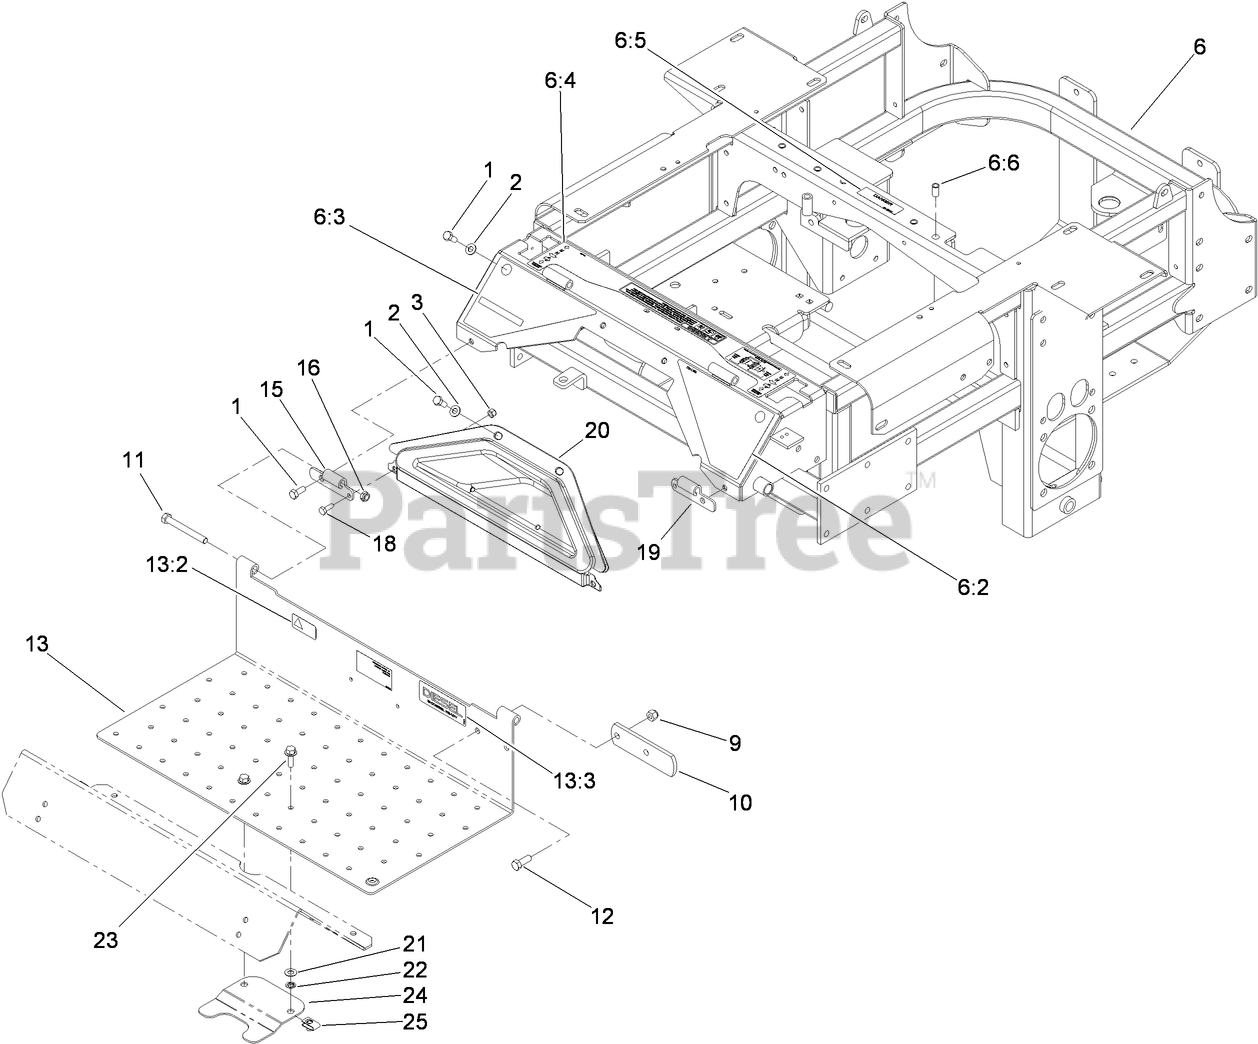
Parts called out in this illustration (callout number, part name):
1	SCREW-HH
2	WASHER-FLAT
3	NUT-LOCK, NI
6	TRACTION FRAME ASM
6:2	DECAL-DANGER, LEFT
6:3	DECAL-WARNING, RIGHT
6:4	DECAL-CONSOLE, TOP (CE)
6:5	DECAL-WARNING
6:6	INSERT-THREADED
9	NUT-LOCK, NI
10	STOP-BRAKE, PARK
11	SCREW-HH
12	SCREW-HH
13	FLOOR PAN ASM
13:2	DECAL-PROTECTION, EAR
13:3	DECAL-DIESEL, BIO-READY
15	Hinge-Floorpan, LH
16	NUT-LOCK, NI
18	SCREW-HH
19	Hinge-Floorpan, RH
20	Pocket
21	WASHER-THRUST
22	NUT-PUSH
23	SCREW-HHF
24	ADAPTER-CAPTIVE
25	NUT-U
